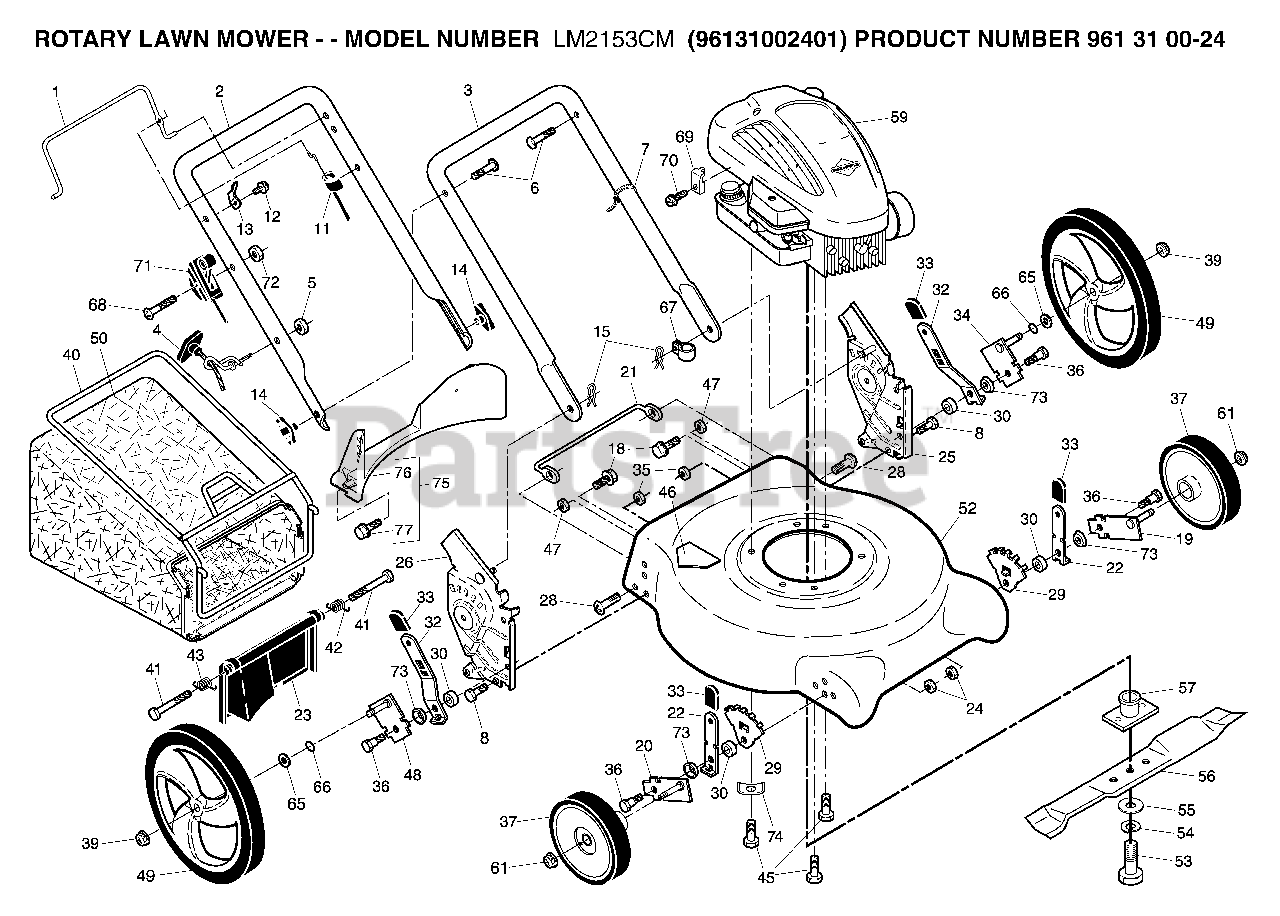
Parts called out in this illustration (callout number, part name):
2	HANDLE.UPPER
3	HANDLE.LOWER.BLACK
4	GUIDE.ROPE.STD.BLK.ZIN
5	NUT
6	BOLT, HANDLE 5/16-18X1.75
7	TIE GUIDE
8	BOLT
11	ENGINE ZONE CONTROL
13	BRACKET UPSTOP
14	KNOB, DEFLECTOR
15	HAIRPIN COTTER
19	AXLE ARM ASSY FRONT LH
20	AXLE ARM ASSY FRONT RH
22	SELECTOR SPRING, FRONT
23	REAR DOOR ASSY
24	LOCKNUT 5/16-18
25	BRACKET.ASM.HAND.HW.21.LT
29	WHEEL ADJ BRACKET FRONT
30	SPACER.HEIGHT.ADJUSTER
32	SPRING.SEL.EXT.21.DOMED.12/14
34	AXLE ARM ASSY REAR LH
35	LOCKNUT 5/16-18
36	SHOULDER BOLT 5/16-18
39	NUT.HEX.FLANGE.3/8-16.LOCKNUT
40	FRAME GRASSBAG
42	SPRING.LH.22.REAR.DOOR.EZ.EMPT
43	SPRING.RH.22.REAR.DOOR.EZ.
45	BOLT 3/8-16X1-1/8
46	DECAL.INTERNATIONL.CUTFINGER
48	AXLE ARM ASSY REAR RH
50	GBAG.
53	SCREW, HEX HD 3/8-24 X 1-3/8
54	LOCKWASHER
55	WASHER,HARDEN
56	BLADE.21.PUSH
57	ADAPTER.BLADE
61	NUT.HEX.FLANGE.3/8-16.LOCKNUT
65	WASHER PM
66	O-RING..070X.487.NEOPRENE
67	CLIP.CABLE.BLK
69	CABLE CLAMP(ENGINE)
70	SCREW.HEX.HEAD.WASHER.10-16
71	THROTTLE CONTROL
72	NUT
73	WASHER FLAT
75	KIT.BAFFLE.REAR.PLASTIC.21.RD
76	BAFFLE.REAR.PLASTIC.21.RD.ECON
77	SCREW.HX.13X.750
